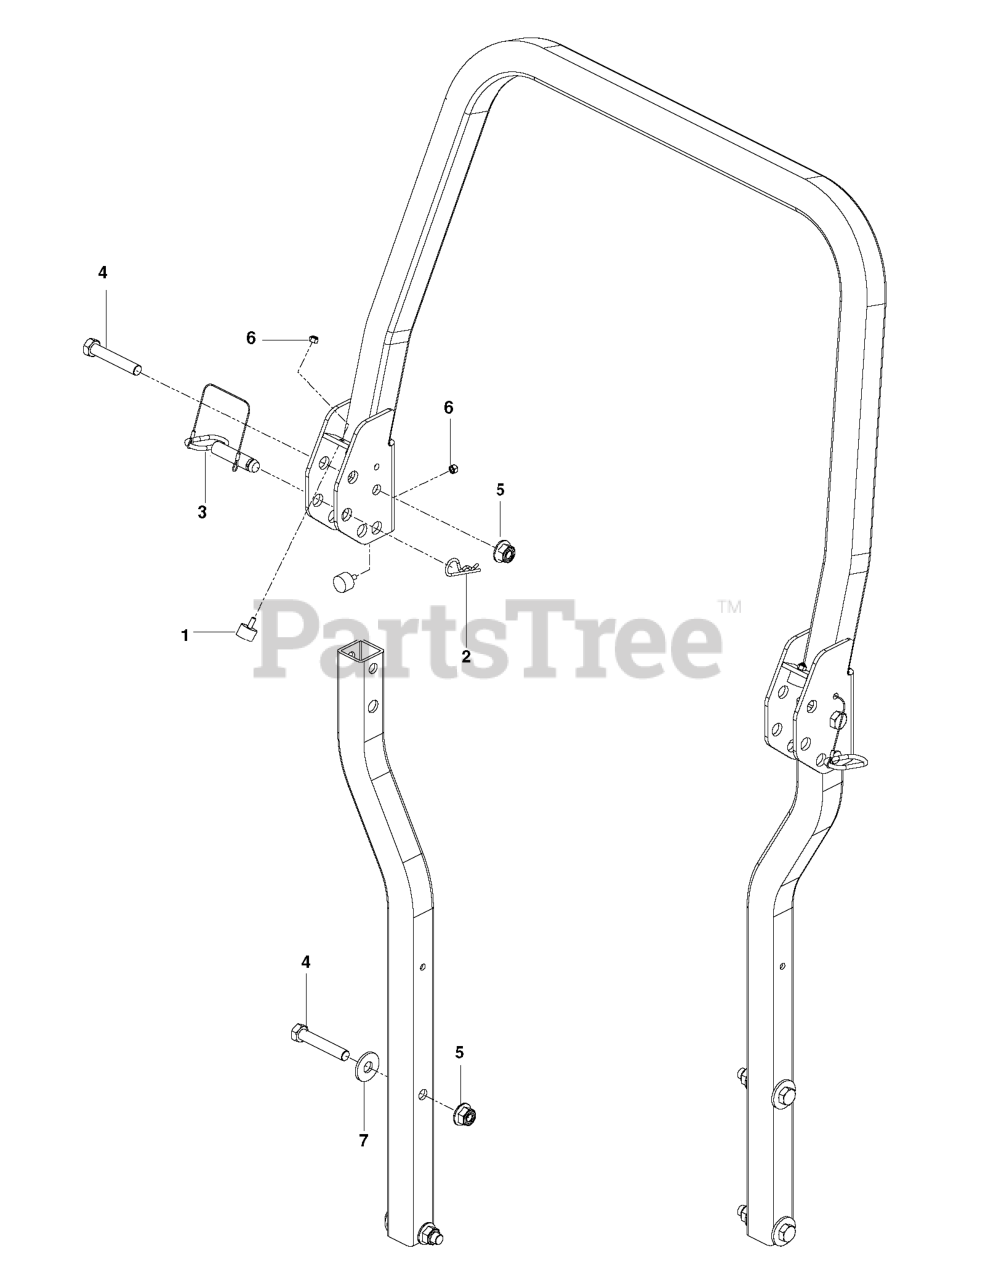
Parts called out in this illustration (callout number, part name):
1	BUMPER, MALE STUD, 1/4-20
2	PIN HAIR .148 X 2-15/16 #210
4	5/8-11 X 3-1/2 HHB GRADE 5
5	NUT 5/8-11 FLG NYLOC ZD
6	LOCKNUT.NYLOC.1/4-20
7	WASHER, 5/8 FLAT
